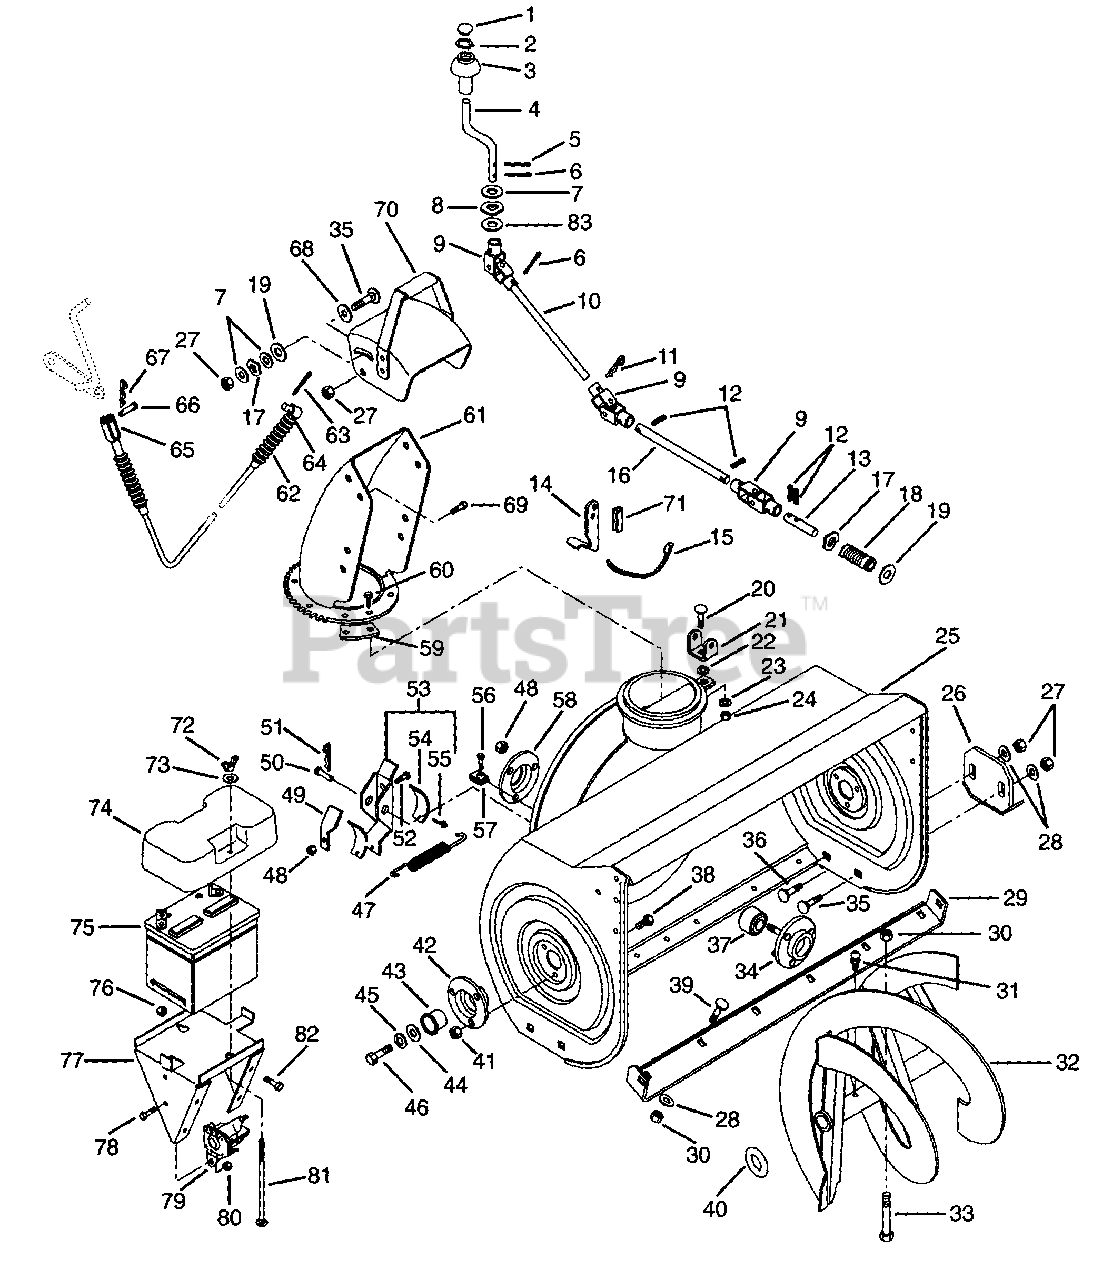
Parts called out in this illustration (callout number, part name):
1	HOLE PLUG
2	RG-RTNG-EXT .375X.010
4	CHUTE CRANK
5	PIN-COTR .12X.75 PL
6	PIN-COTR .12X1.0 PL
7	@WSHR-FL-STL.406X.812X.065 YWZ
8	SPRING WASHER
9	UNIVERSAL JOINT ASS'Y
10	CHUTE CRANK ROD
11	PIN-HAIR INT .08X.38X1.42 YWZC
12	PIN-ROLL .125X.75
13	WORM SHAFT
14	CHUTE CRANK BRACKET
15	CABLE TIE LG 8-7/8
17	WAVE WASHER .406X.750X.063FH
17	WAVE WASHER .390X.655X.110
18	WORM GEAR L.H.
19	WSHR-PLASTIC .390X.875X.062
20	BLT-RDHDSQNK .31-18X.75 SHT PL
21	WORM CLEVIS
22	WSHR-LK .250X.047 LT YWZC
23	WSHR-LOCK .31X.078 REG YWZC
24	@NUT-HEX .31-18 YWZC
25	BLOWER HOUSING W/DECALS 36
25	BLOWER HOUSING W/DECALS 28
25	HOUSING, BLOWER W/DECALS-24"
26	RUNNER
26	RUNNER - SKID SHOE
27	@NUT-LK-CTR .38-16 YWZC
28	@WSHR-FL-STL.38X.875X.083 YWZC
29	SCRAPER BLADE 24"
29	SCRAPER BLADE 32"
29	SCRAPER BLADE 28"
29	SCRAPER BLADE 36"
29	BLADE, SCRAPER 24"
30	@NUT-LK-CTR .31-18 YWZC
31	FTG-LUBE .25-28X.256 YWZC
32	RAKE, RIGHT-32"(1ID X 15.75OD)
32	RAKE, LEFT-32"(1"ID X 15.75OD)
32	RAKE, RIGHT-24"(1ID X 14.75OD)
32	RAKE, LEFT-24"(1"ID X 14.75OD)
32	RAKE, RIGHT-28"(1ID X 15.75OD)
32	RAKE, LEFT-28"(1"ID X 15.75OD)
32	RAKE, RIGHT-36"(1ID X 15.75OD)
32	RAKE, LEFT-36"(1"ID X 15.75OD)
32	RAKE, RIGHT-24"(1ID X 15.75OD)
32	RAKE, LEFT-24"(1"ID X 15.75OD)
33	SHEAR BOLT SERVICE ASSEMBLY
34	BEARING FLANGE
35	BLT-RHHDSQSHNK .38-16X.75 G2YZ
36	BLT-RDHDSQSHNK .38-16X1.00 PL
37	BRG-BALL1.0X2.0X.56
37	BRG-BALL .750X1.750X.50
38	BLT-SERNK SL .25-20X.50 PL
39	@BLT-RHDSSQNK .31-18X.62 G5YZ
40	WSHR-FL-STL 1.010X1.505X.062YZ
41	@NUT-LK-CTR .25-20 YWZC
42	BEARING SUPPORT
43	BSHG-FLG 1.000X1.12X.62X1.50BR
44	WSHR-FL-STL.511X1.441X.125 YWZ
45	@WSHR-LK .50X.125 REG YWZC
46	@BLT-HEX .50-13X1.00 GR5 YWZC
47	SG-TENS .062X.56X8.0 WLD 11
48	@NUT-LK-CTR .25-20 YWZC
49	ARM EXTENSION
50	PIN-CLEV .371X1.16 YWZC
51	@PIN-CTR .06X.75 EXTPRSQCT YWZ
52	BLT-HEX .25-20X.63 PL GR2
53	BRAKE ARM ASSEMBLY
54	BRAKE LINING
55	RVT-TBLR .187X.437 RH ST PL
56	BLT-SERHFWH .38-16X.75 YWZC
57	NUT-RETNR .38-16 TINRMAN
58	BEARING FLANGE
59	CHUTE CLAMP
60	@SCR-TAP 12-24X.50 HWH TR YWZC
61	DISCHARGE CHUTE - HIGH
61	DISCHARGE CHUTE
62	CONTROL CABLE
63	@PIN-CTR .09X.75 EXTPRSQCT YWZ
64	PIVOT
65	CLEVIS
66	CLEVIS PIN
67	PIN-COTR .06X.50
68	@WSHR-FL-STL.406X.812X.065 YWZ
69	@BLT-HEX .38-16X.75 GR5 YWZC
70	CHUTE DEFLECTOR W/DECAL
70	DEFLECTOR W/DECAL
72	NUT-WING .250-20 YWZC
73	@WSHR-FL-STL.281X.62X.065 YWZC
74	COVER, BATTERY
75	BATTERY
76	@NUT-LK-CTR .25-20 YWZC
77	TRAY, BATTERY
77	ST BATTERY TRAY 24
78	BLT-HEX .25-20X.63 PL GR2
79	SOLENOID
80	@NUT-LK-CTR .25-20 YWZC
81	BLT-RDHDSQNK .25-20X7.00
82	@BLT-HEX .25-20X.75 GR5 YWZC
83	WSHR-FL-STL .382X.812X.023YWZC
